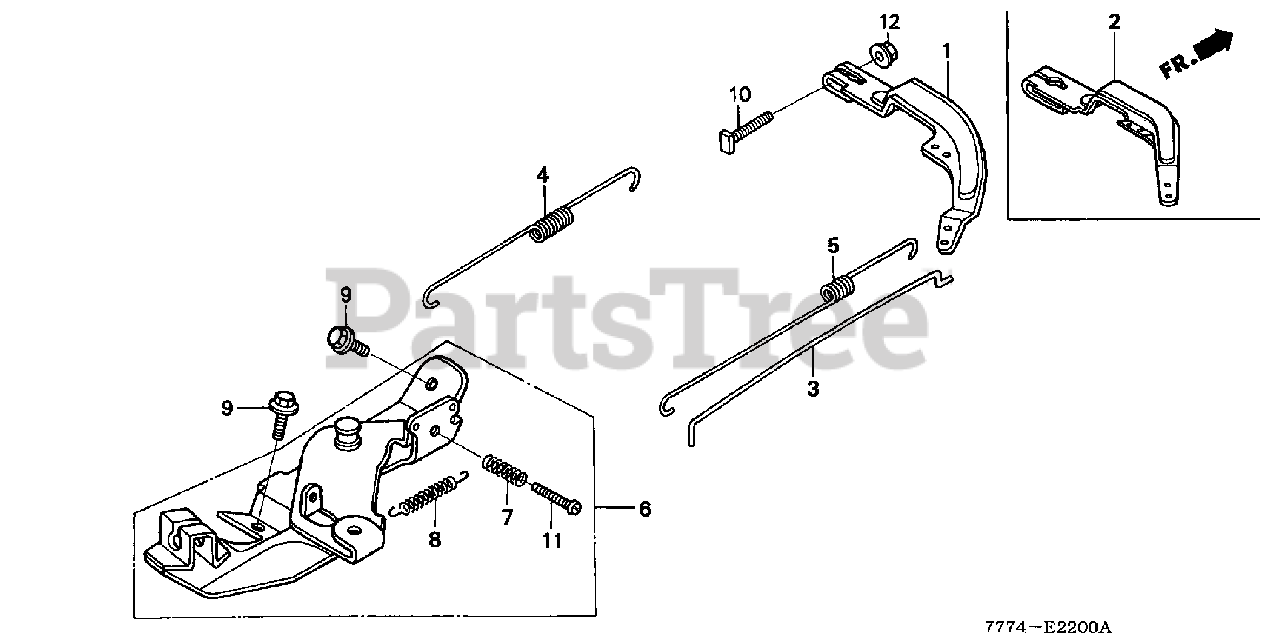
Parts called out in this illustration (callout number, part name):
1	ARM, GOVERNOR
3	ROD, GOVERNOR
4	SPRING, GOVERNOR
5	SPRING, THROTTLE RETURN
6	CONTROL ASSY.
7	SPRING, CONTROL ADJUSTING
8	SPRING, CABLE RETURN
9	BOLT, FLANGE (6X12) (CT200)
10	BOLT, GOVERNOR ARM
11	SCREW, PAN (5X28)
12	NUT, FLANGE (6MM)
